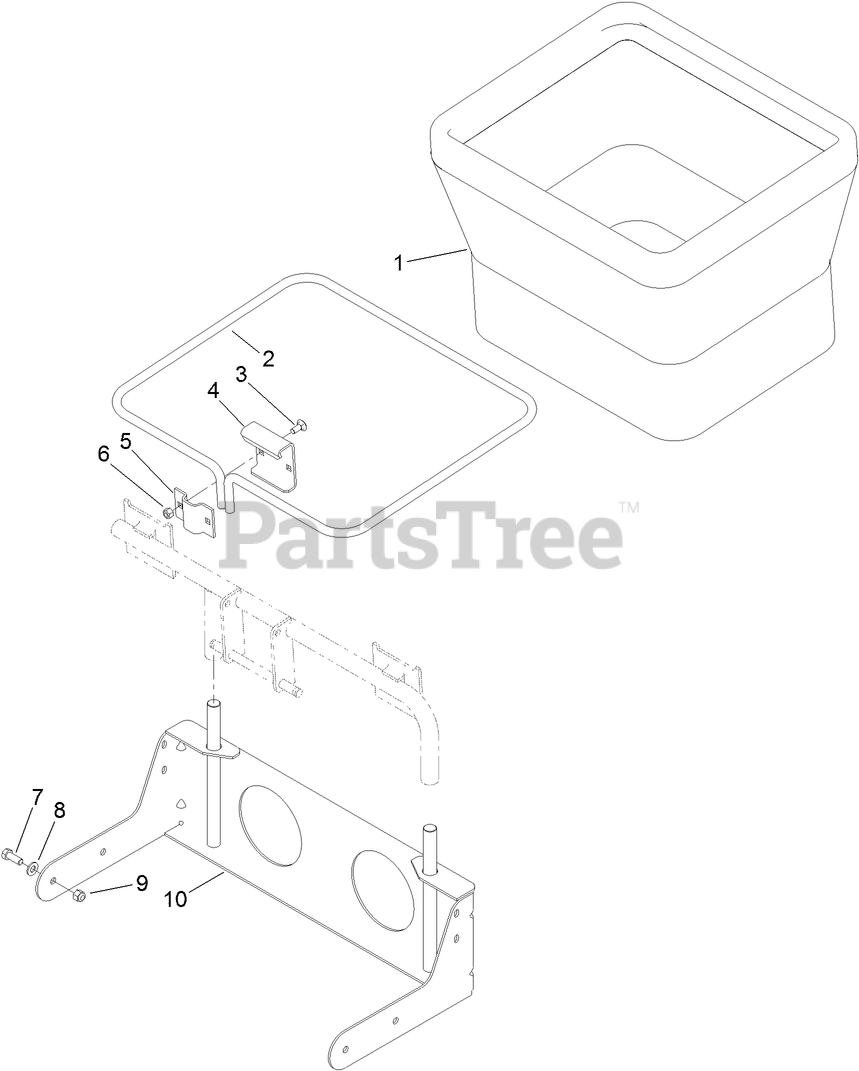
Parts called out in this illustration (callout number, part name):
2	FRAME-BAG
3	BOLT-CARR
4	HANGER-BAG
6	NUT-LOCK, NI
7	SCREW-HH
8	WASHER-FLAT
9	NUT-LOCK, NI
